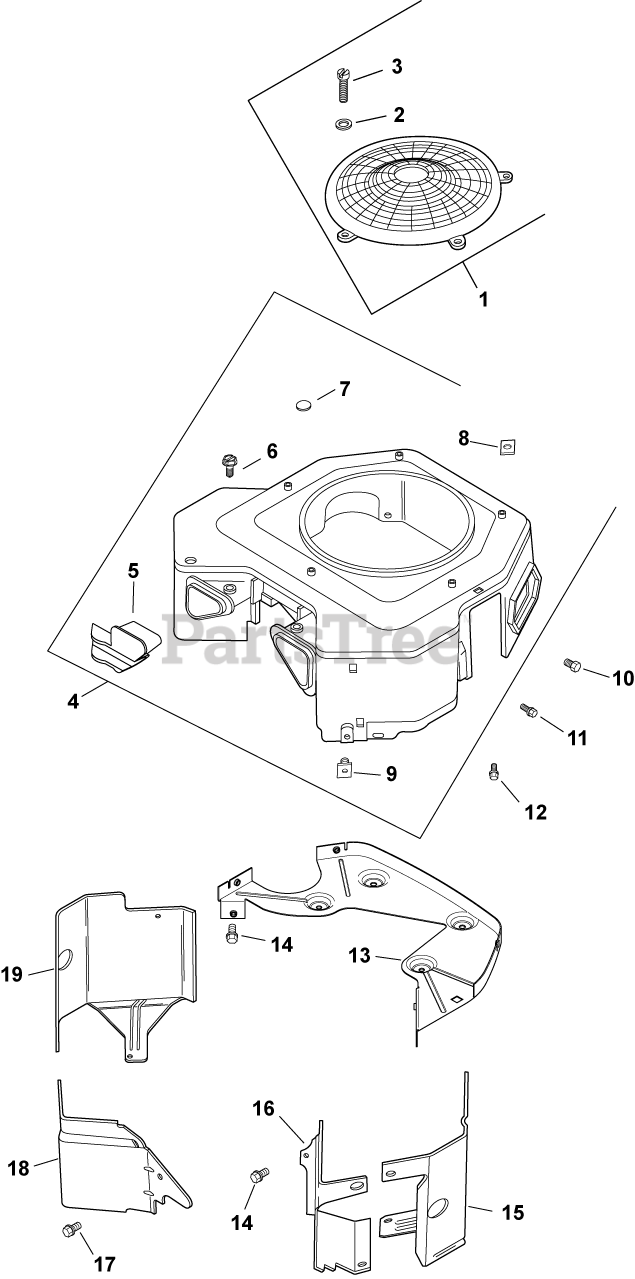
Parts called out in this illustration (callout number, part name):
1	KIT, FIXED GUARD
2	WASHER, FLAT 7/32"
3	SCREW, LBD SCKT PAN M5X0.8X10
4	KIT, BLOWER HOUSING ASSEMBLY USE 24 027 490-S
5	COVER, BLOWER HOUSING-USE 24 096 119-S
6	SCREW, WSH HD TAP #8-18X1/2"
7	PLUG, BUTTON 9/16
8	NUT, PLASTIC
9	NUT, PLASTIC (KM)-USE 25 100 37-S
10	SCREW - USE M-545016-S
11	SCREW,FLG THD FRM M5X0.8X16-(#25086398S)
12	SCREW, FLG THD FRM M5X.8X20-(#25086399S)
13	PLATE, BACKING (OIL COOLER)-USE 24 146 5
14	SCREW,FLG THD FRM M6X1.0X16-(#25086397S)
15	BAFFLE,VALLEY #2SIDE(KM)-USE 24 063 88-S
16	BAFFLE, VALLEY #2 SIDE-USE 24 063 94-S
17	SCREW, FLG THD FRM M5X.8X10
18	BAFFLE, VALLEY (CV)-USE 24 063 93-S
19	BAFFLE, RIGHT BARREL-USE 24 063 85-S
